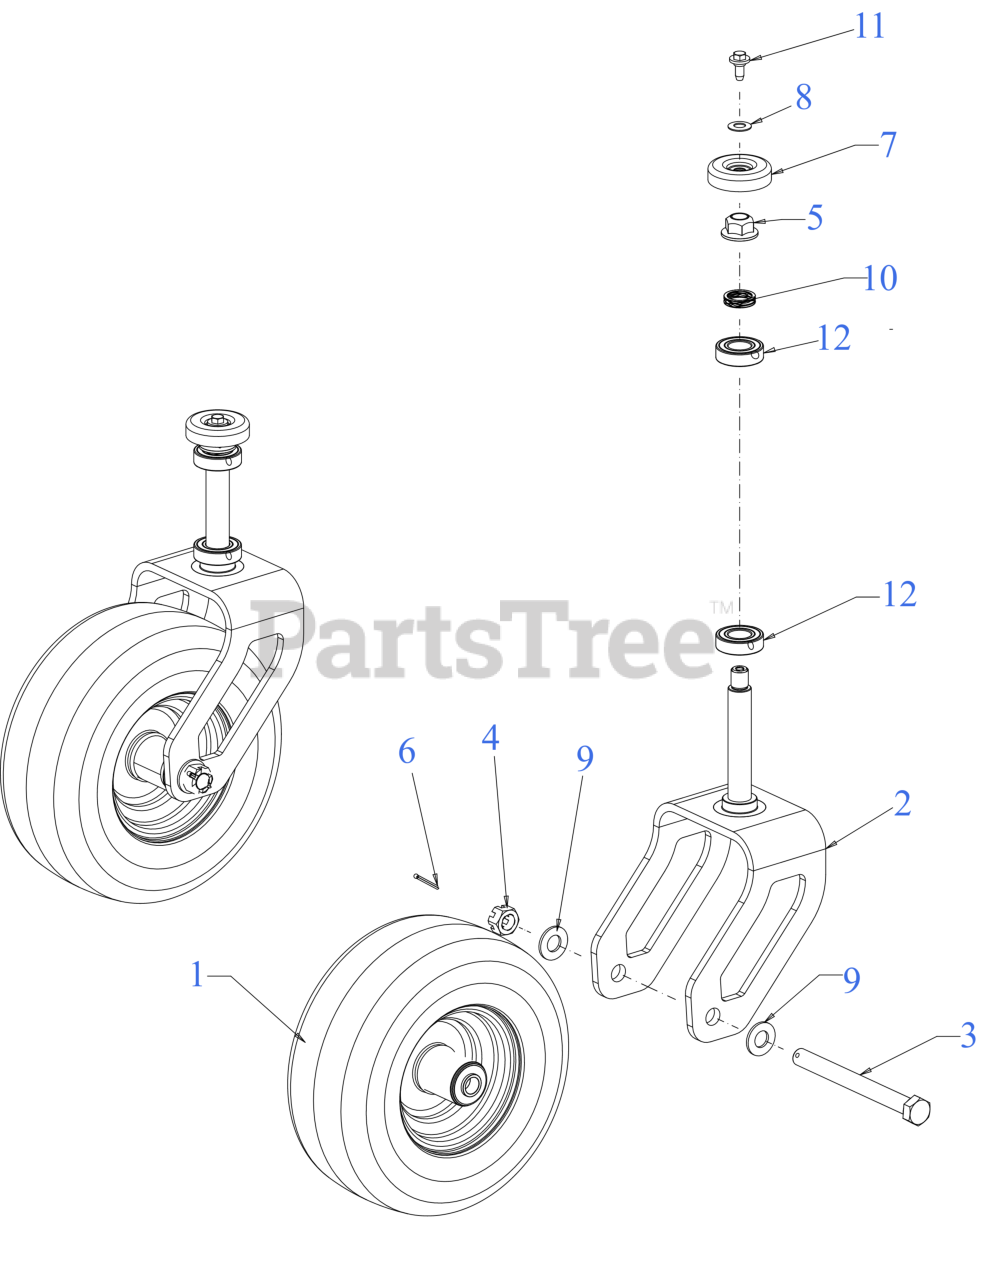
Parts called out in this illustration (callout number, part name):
1	WHEEL ASSEMBLY (13x5-6)
1	SEALED BALL BEARING
2	YOKE
3	HEX HEAD CAP SCREW 3/4-16 x 7.75
4	HEX NUT CASTLE 3/4-16
5	FLANGE LOCK NUT 3/4-16 TOP LOCK
6	COTTER PIN-5/32 DIA
7	AXLE CAP 2.5"
8	BELL WASHER
9	FLAT WASHER
10	WAVE WASHER
12	BALL BEARING (1.0 x 52 x 15)
